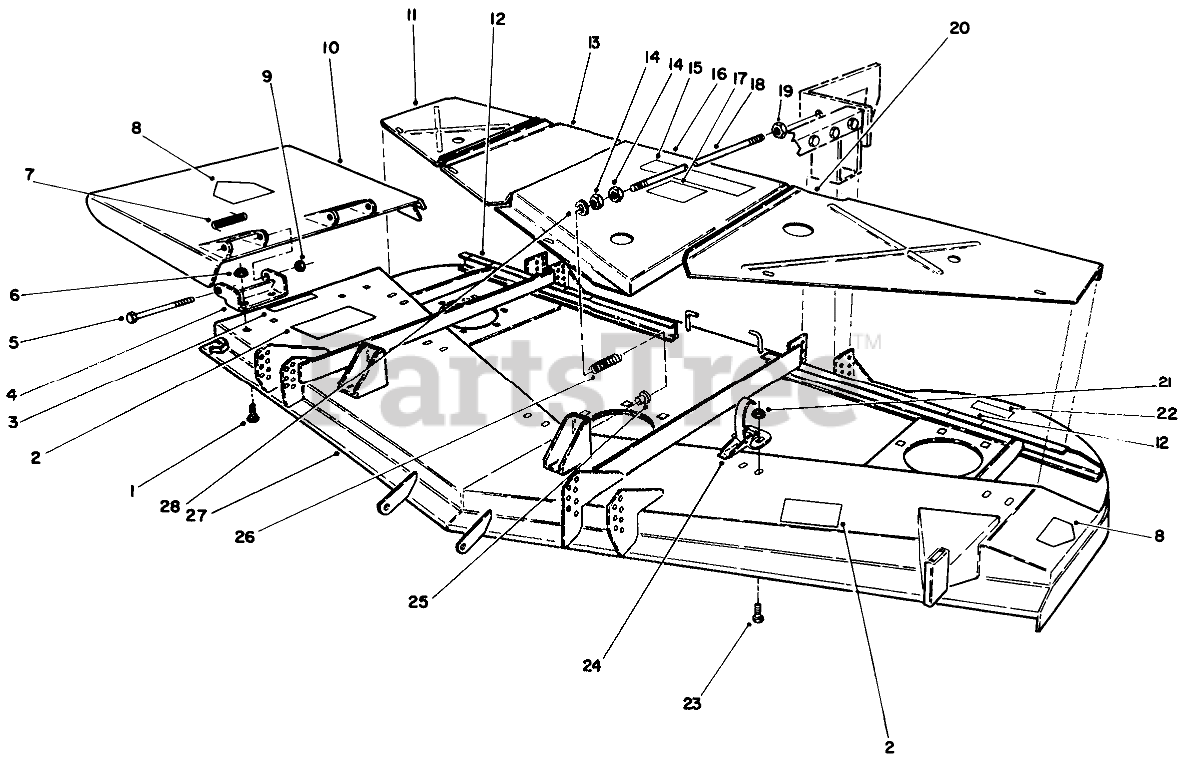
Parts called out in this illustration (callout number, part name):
1	SCREW-CARR
2	DECAL-DANGER, THROWN OBJECT
3	DECAL-DANGER
4	Bracket-Hinge
5	SCREW-HH
6	NUT-HHF, WHIZ
7	SPRING
8	DECAL-DANGER
9	NUT-HEX
10	Deflector
11	Cover-Deck R.H.
12	DECAL-DANGER
13	Cover-Deck, Center R.H.
14	NUT-JAM
15	DECAL-PROLINE
16	Cover-Deck, Center L.H.
17	DECAL
18	ADJUSTING SHAFT
19	NUT-LOCK, NI
20	Cover-Deck L.H.
21	NUT-LOCK, FLANGE
22	DECAL-TORQUE
23	SCREW-HWH
24	CLAMP-SLOTTED
25	BUSHING-FLANGE
26	SPRING
27	Deck Assembly
28	WASHER
